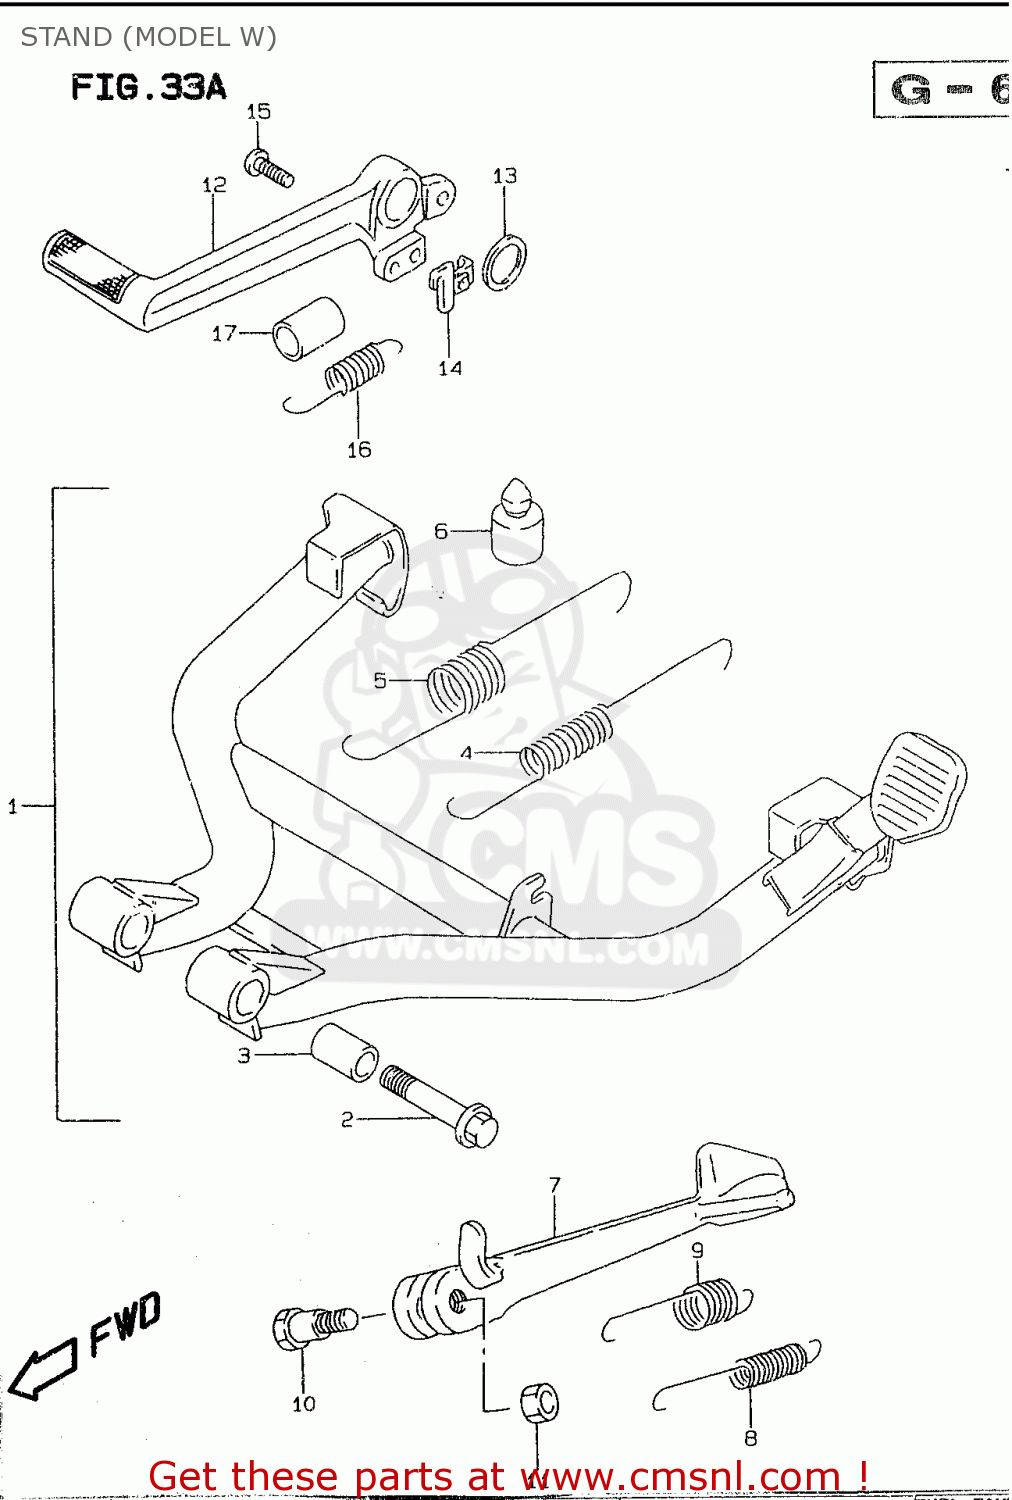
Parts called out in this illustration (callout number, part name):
1	STAND SET,CTR
2	BOLT(10X48)
3	SPACER(10X16X25.5)
4	SPRING
5	SPRING OUTER
6	CUSHION
7	STAND,PROP
8	SPRING
9	SPRING
10	BOLT(10X34)
11	NUT
12	PEDAL,BRAKE
13	WASHER(18X24X1)
14	BRACKET,STOP LAMP SWITCH SPR
15	SCREW
16	SPRING
17	TUBE,BRAKE SPRING GUIDE
